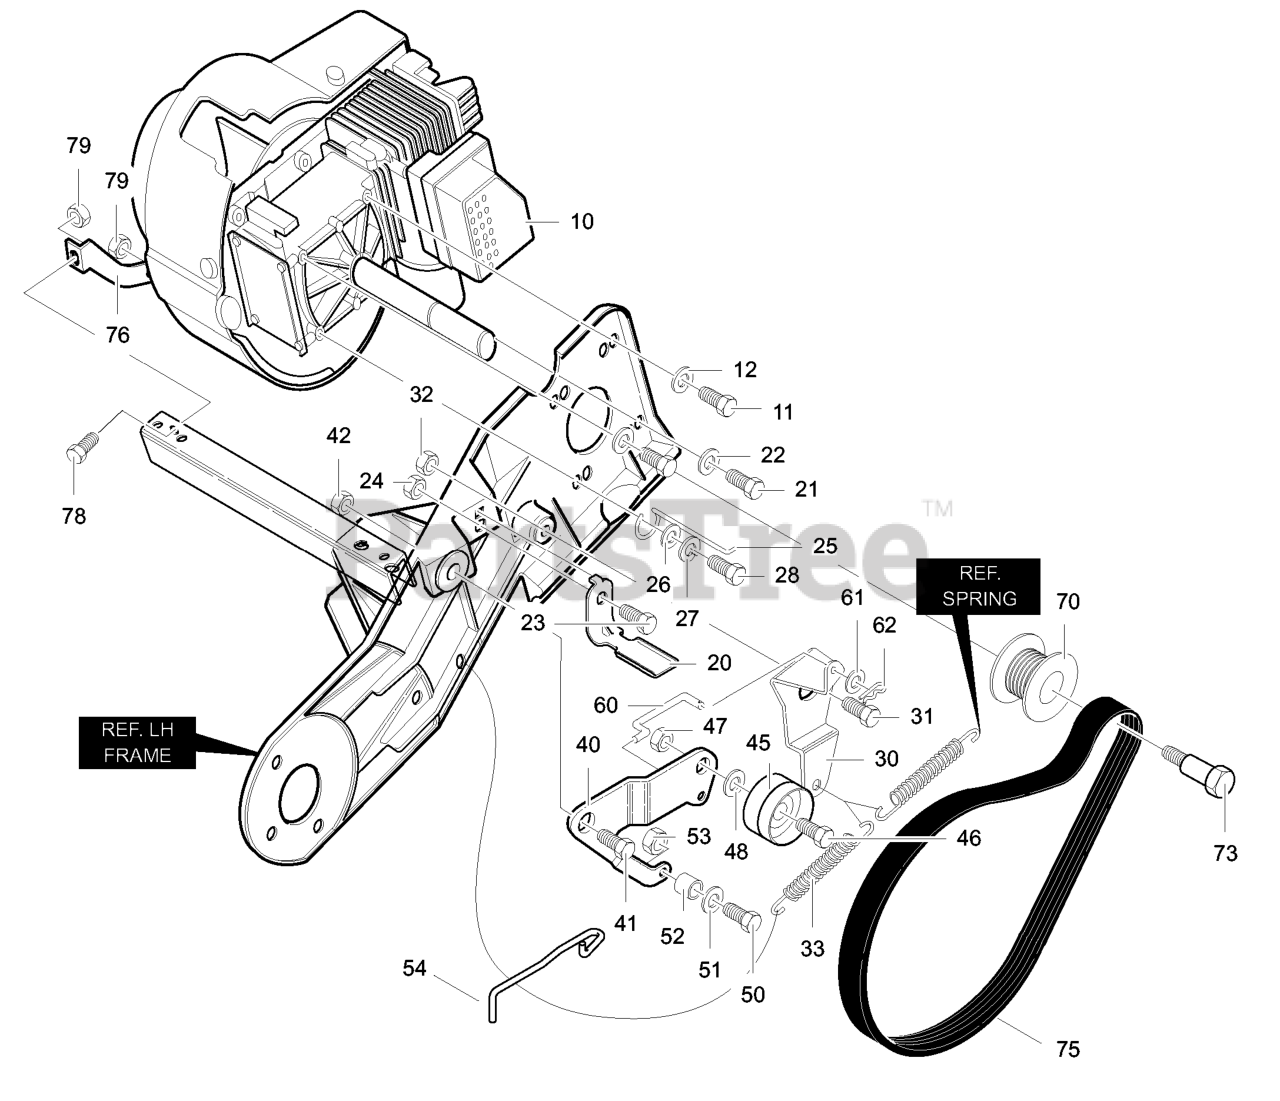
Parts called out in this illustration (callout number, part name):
10	ENGINE
11	SCREW
12	WASHER
20	LF PAD, BRAKE
21	SCREW
22	WASHER
23	SCREW,1/4-20X.63
24	NUT, 1/4-20
25	GUIDE, BELT
26	WASHER, FLAT
27	WASHER
30	ARM, IDLER
32	NUT, 5/16-18
33	SPRING, EXTENSION
40	LF ARM, IDLER
42	NUT, 5/16-18
45	PULLEY, IDLER
47	NUT
48	WASHER, FLAT
50	SCREW, 1/4-20X2.00
51	WASHER, FLAT
52	ROLLER, PINCH
53	NUT, 1/4-20
54	WIRE, BRAKE
60	ROD, CLUTCH
61	WASHER, FLAT
62	PIN, COTTER
73	BOLT, SHOULDER
76	BRACKET, SUPPORT
78	SCREW
79	NUT, 5/16-18
